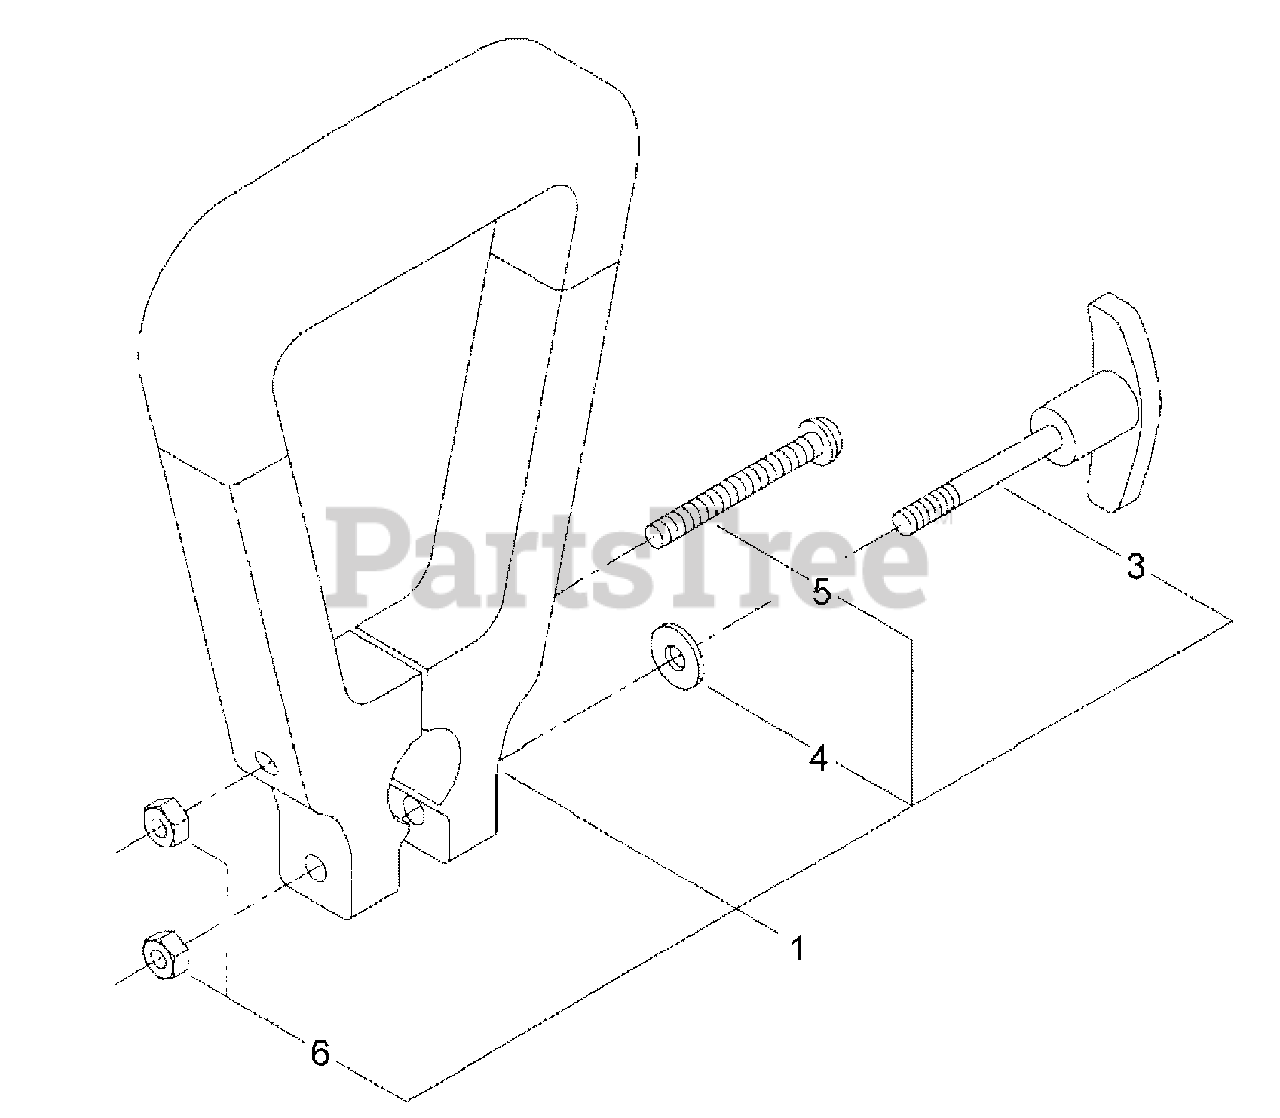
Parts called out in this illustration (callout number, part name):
1	HANDLE ASSY
3	KNOB, SCREW
4	WASHER 6
5	SCREW 6
6	NUT, HEX M6
